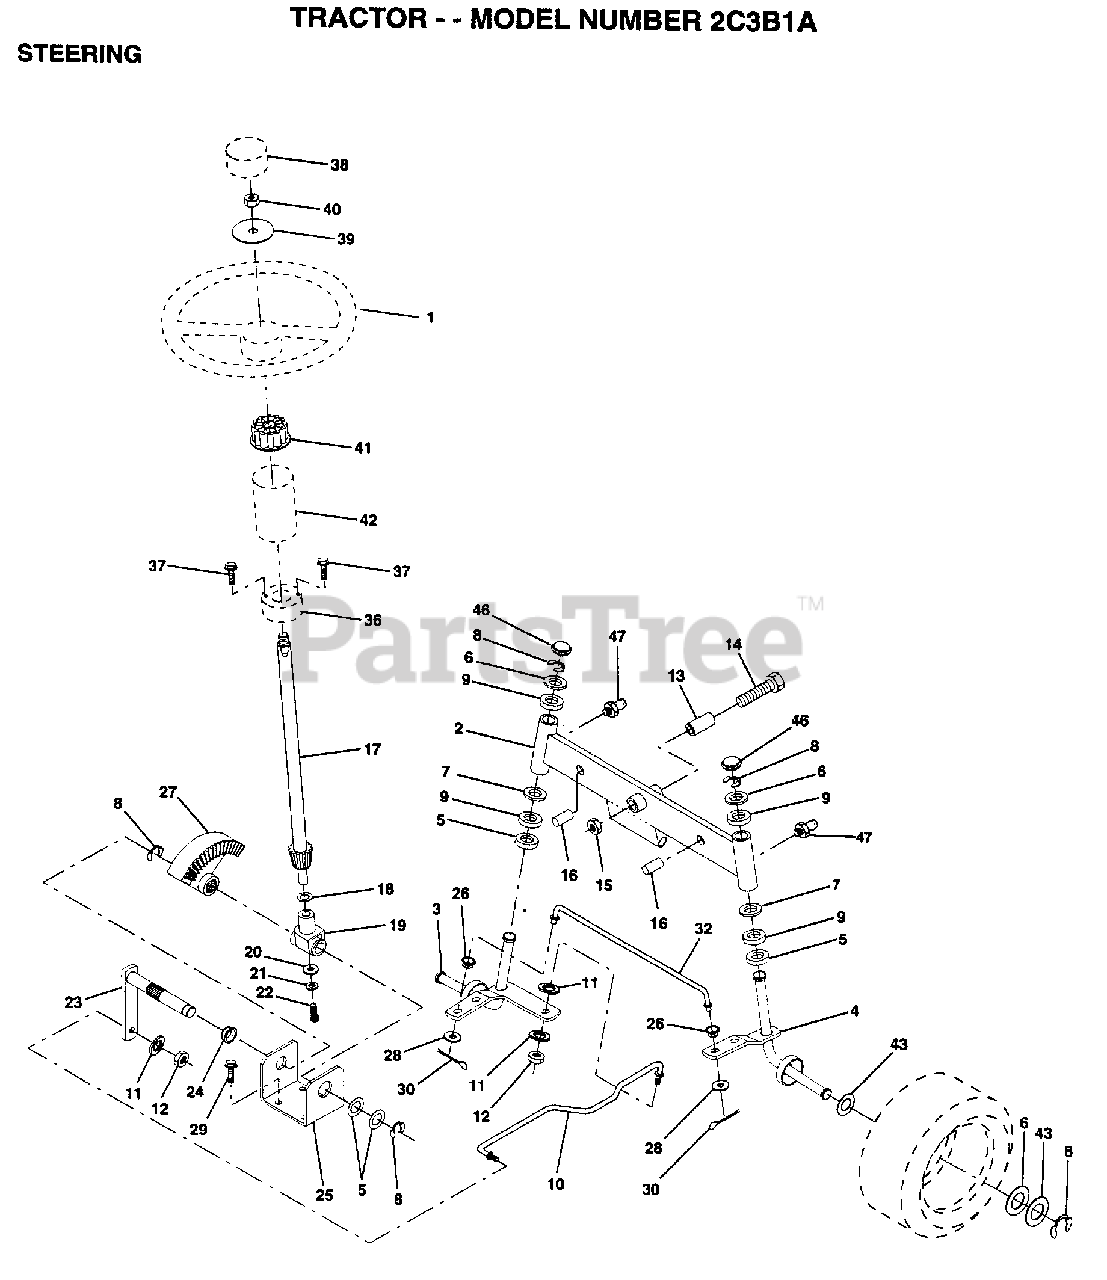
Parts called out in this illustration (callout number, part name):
2	AXLE ASM FRONT
3	SPINDLE LH
4	SPINDLE RH
5	WASHER .T
6	WASHER
7	WASHER
8	RING
9	COL. SRTG. BEAR.
11	LOCKWASHER
14	BOLT HEX 5/8-11
15	"NUT-LOC,FLANGE LT"
16	AXLE PIN
17	SHAFT ASM
18	THRUST WASHER
20	Washer Shim 1/4 x 5/8 x .062
21	LOCKWASHER
22	"SCREW,SPECIAL"
24	NYLINER T (7283A)
25	BRKT,STEERING
26	BUSHING.DRAGLINK (3 2)
27	GEAR SECTOR
28	WASHER
29	SCREW
30	COTTER PIN
32	TIE ROD
38	ST WHL INSERT CAP
39	WASHER T
40	GRIPCO NUT
41	ADAPTER-WHEEL LT
42	TUBE, STR SHAFT
43	WASHER (2513009)
46	CAP
47	ZERK M
